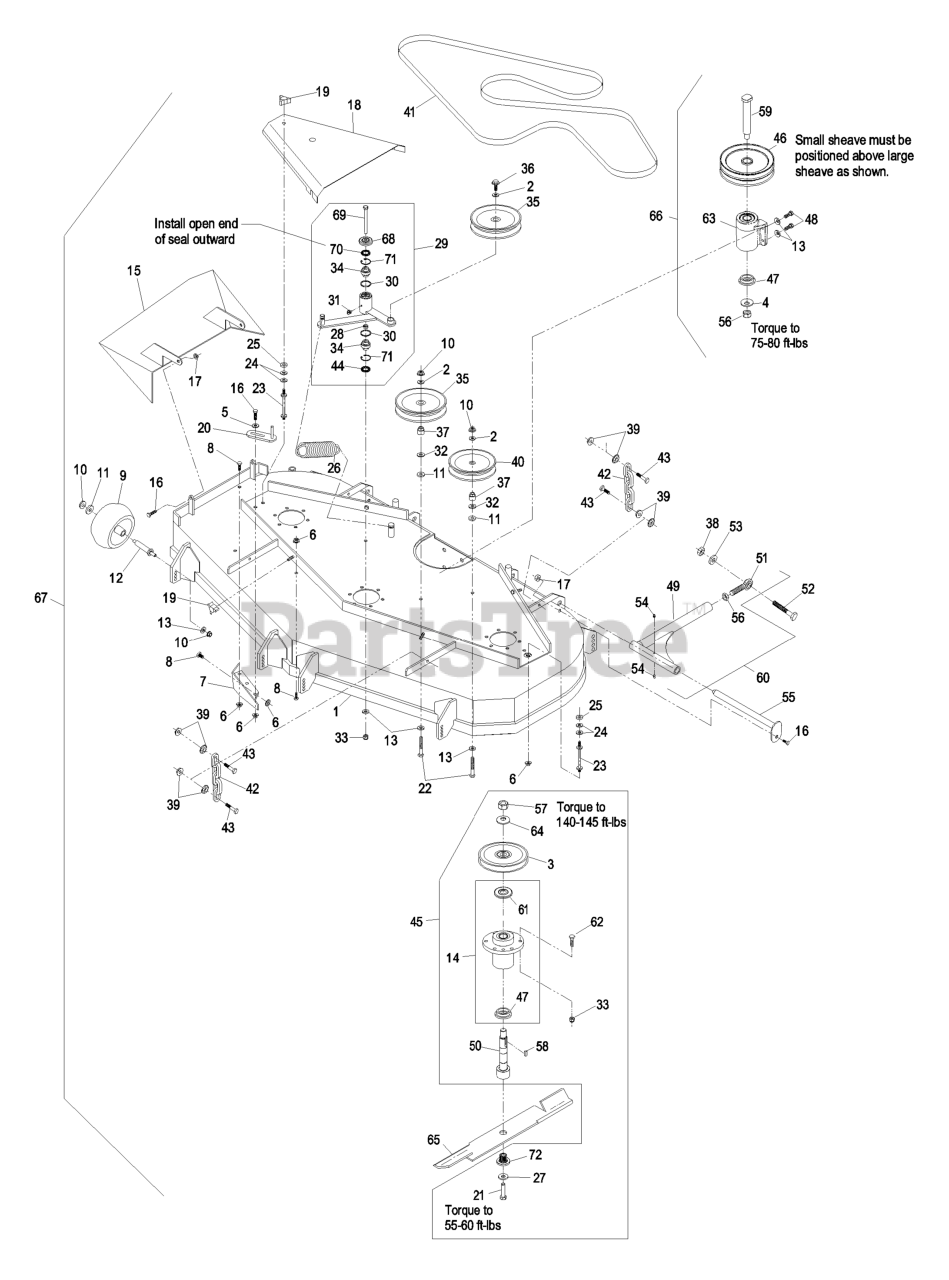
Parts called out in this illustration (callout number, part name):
1	ASM,DECK W/DECALS LZ524
2	WASHER-FLAT
3	SHEAVE,BLADE DRIVE 6.30
4	WASHER-SPRING
5	WASHER-SPRING
7	WLD,BAFFLE DISCHARGE
8	SCREW-HH
9	ROLLER-SCALP, ANTI
10	NUT-HHF, WHIZ
13	WASHER-BELLEVILLE
14	KIT, CUTTER HOUSING
15	WLD,CHUTE DICHARGE 524
16	SCREW-HH
17	NUT-LOCK, NI
18	SHIELD,BELT 52
19	KNOB-3 PRONG
20	GUIDE-BELT
21	SCREW-HH
22	SCREW-HH
23	STUD-SHIELD, BELT (SHORT)
24	WASHER-FLAT
27	WASHER-SPRING
29	KIT,DECK IDLER LZ/XP
31	FITTING-GREASE, 90 DEG
32	WASHER-FLAT
33	NUT-LOCK, NI
34	BEARING-SPHERICAL
36	SCREW-HHF
37	BUSHING-IDLER
38	NUT-HEX
40	PULLEY-IDLER
41	BELT,BLADE DRIVE 52
42	CHAIN-LIFT, DECK
43	SCREW-HH
44	SEAL-LIP, DOUBLE
45	ASM, CUTTER HSG COMPLETE
46	SHEAVE,JACKSHAFT - DBL
47	SPACER-GUARD, BOTTOM
48	SCREW-HH
50	KIT, SPLINED SPINDLE 103-
51	BALLJOINT-SPHERICAL
52	SCREW-HH
53	WASHER-LOCK
54	FITTING-GREASE
55	PIN-STRUT
56	NUT-HEX
57	NUT-HH
59	JACKSHAFT
60	STRUT ASM
61	GUARD-BEARING, TOP
62	SCREW-HH
66	KIT,JACKSHAFT 52-3750
67	Asm, Deck Complete
68	GUARD-TOP
69	SCREW-HH
70	SEAL-LIP, SINGLE
71	RING-SNAP
72	BUSHING,SPLINED
